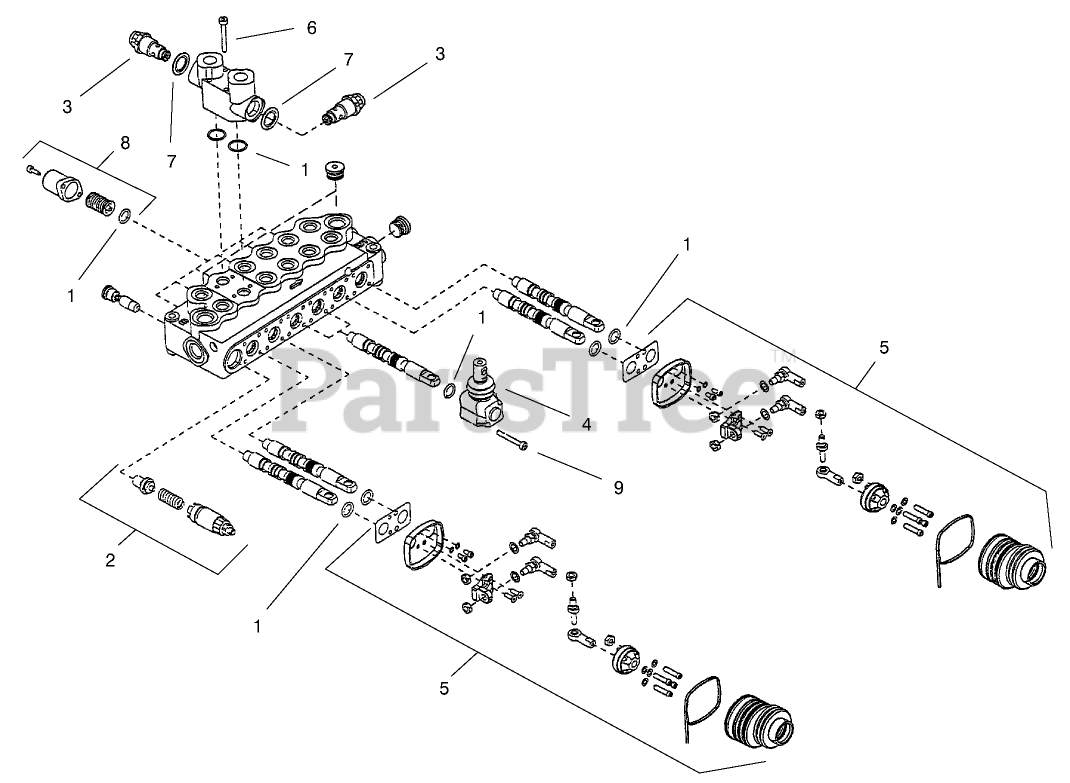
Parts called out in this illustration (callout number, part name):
1	VALVE SEAL KIT
2	RELIEF VALVE KIT
3	CARTRIDGE-RELIEF
4	LEVER KIT
5	JOYSTICK KIT
7	WASHER
8	HIGH FORCE SPRING KIT
